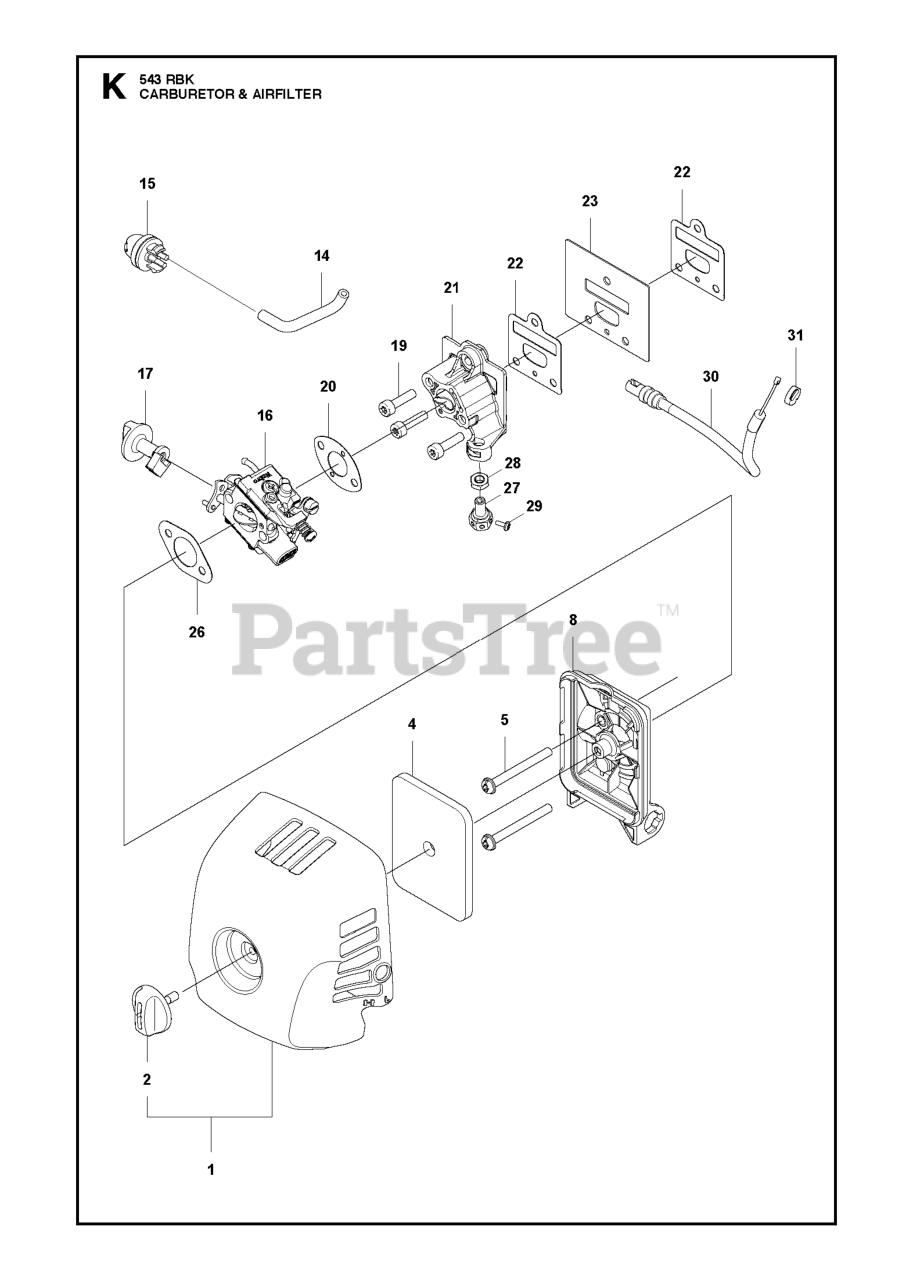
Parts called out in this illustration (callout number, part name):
1	AIR FILTER COVER ASSY GZ40N7
2	TURNING KNOB GZ40N7
15	PRIMARY BTN
16	CARBURETOR ASSY WTEA-7B
22	GASKET
27	SCREW CABLE ADJUST
